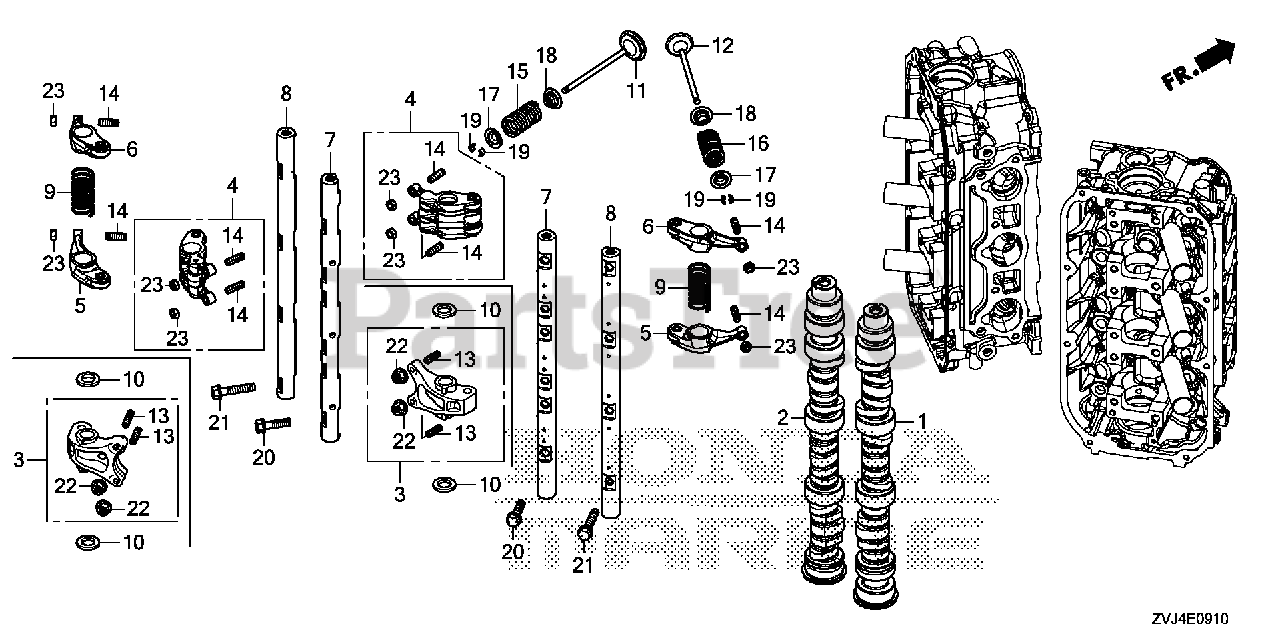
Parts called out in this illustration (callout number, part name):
1	CAMSHAFT, R.
2	CAMSHAFT, L.
4	ARM ASSY., IN. ROCKER
5	ARM A, EX. ROCKER
6	ARM B, EX. ROCKER
7	SHAFT, IN. ROCKER ARM
8	SHAFT, EX. ROCKER ARM
9	SPRING, ROCKER ARM
11	VALVE, IN.
12	VALVE, EX.
14	SCREW, TAPPET ADJUSTING
15	SPRING, VALVE (PINK) (NIPPON HATSUJO)
16	SPRING, EX. VALVE (YEL/GRN) (ASSOCIATE)
17	RETAINER, VALVE SPRING
18	SEAT, VALVE SPRING
19	COTTER, VALVE (FUJI VALVE)
20	BOLT, FLANGE (8X30)
21	BOLT, FLANGE (8X40)
23	NUT, TAPPET ADJUSTING
